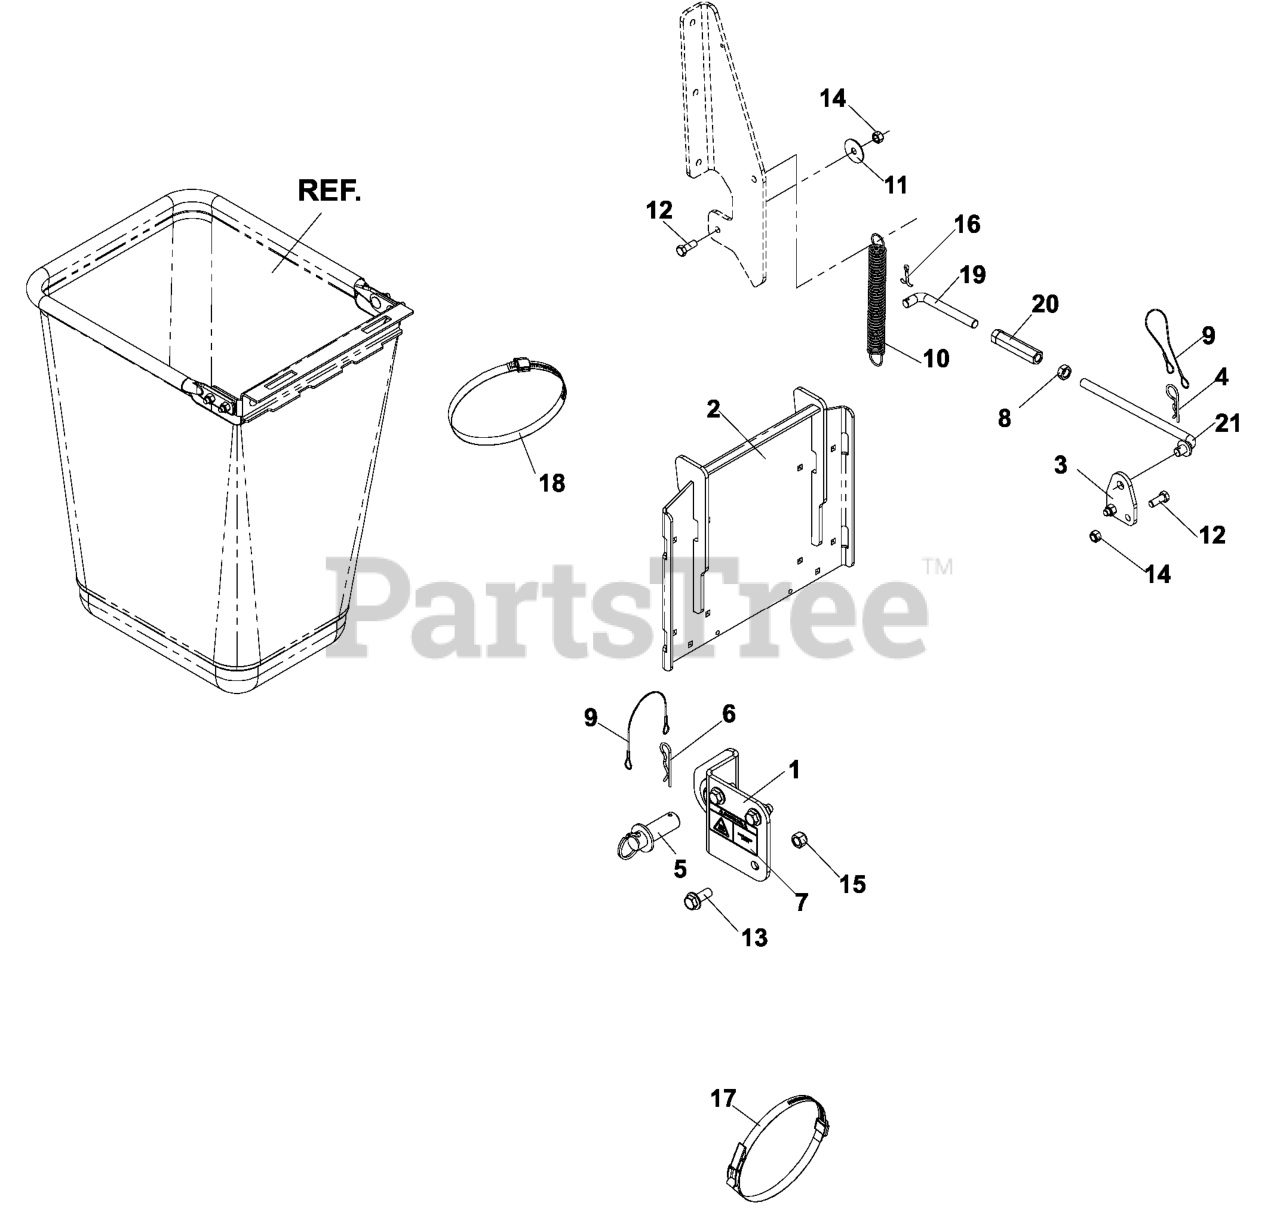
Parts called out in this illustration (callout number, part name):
1	HITCH BRACKET
2	REAR GUARD WELDMENT
3	SUPPORT BRACKET
4	HAIRPIN #4
7	DECAL, HOT SURFACE
8	NUT 1/2-20 HEX JAM ZD
11	WASHER, FRICTION
12	HCS 3/8-16X1.GRD.5.ZD
13	HCS 1/2C X 1 1/4 SERRATED HEAD
14	NUT 3/8-16 NYLOC
15	NUT 1/2-13 HEX NYLOC ZD
16	COTTER PIN
17	OVER CTR BAND
18	HOSE CLAMP 4-1/8 TO 7"
19	SUPPORT LINKAGE, LH
20	TURNBUCKLE, 1/2
21	SUPPORT LINKAGE, LRG
